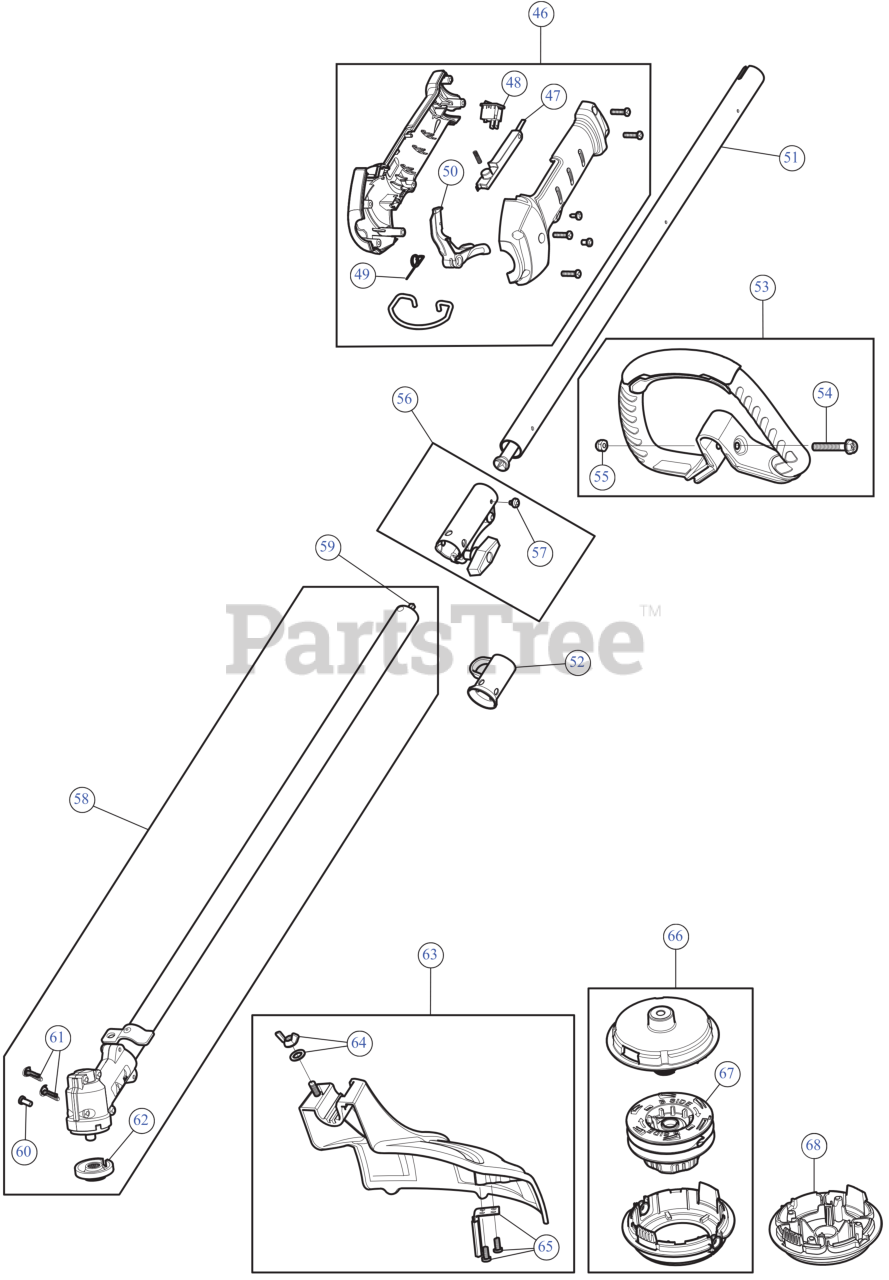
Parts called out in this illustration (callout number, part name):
46	THROTTLE GRIP ASM
47	LEVER LOCK OUT
48	SW, MOMENTARY ON/O
49	SPRING TRIG
50	THROTTLE TRIGGER
51	UPPER BOOM
52	HANGER
53	HANDLE DLX
54	BOLT 1/4-20X1 1/2
55	NUT 1/4-20 NYLOC
56	COUPLER ASSEMBLY
57	SCREW, 10-32X.250 TA
58	LOWER BOOM
59	LOWER DRIVE SHAFT
60	SCREW, 8-32 x .312 P
61	SCREW #
62	CUTTING HEAD SPACER
63	GUARD/BLADE ASSEMBLY
64	BLADE GUARD MOUNTING HARDWARE
65	BLADE ASSEMBLY W/HDW
66	COMPLETE HEAD ASSEMBLY
67	BUMP KNOB
68	CAP ASSEMBLY W/PLUG
